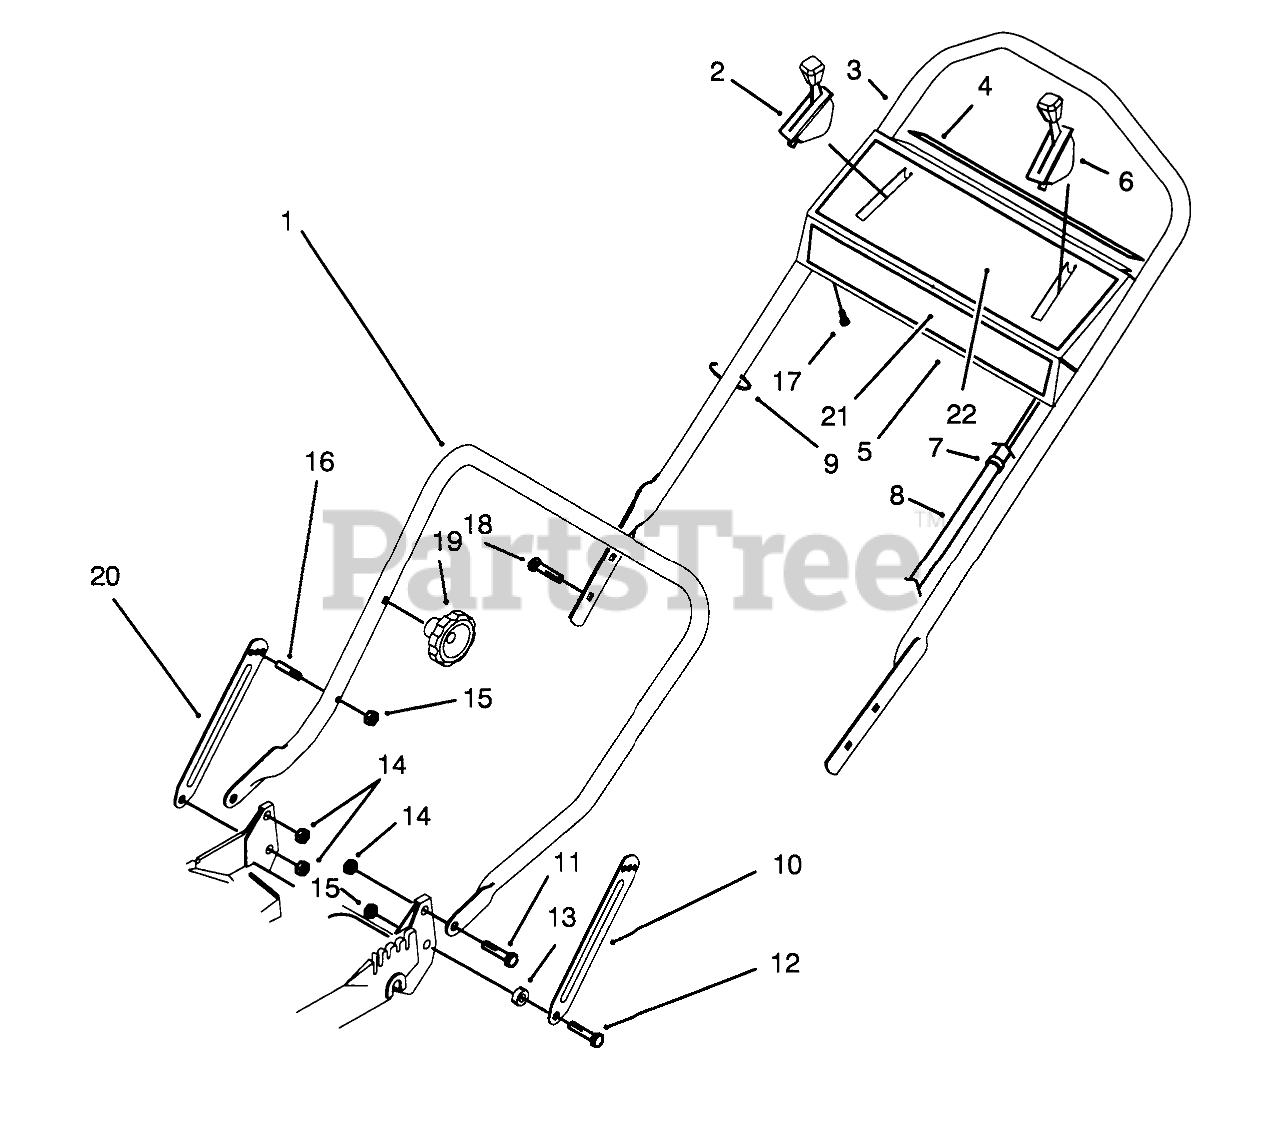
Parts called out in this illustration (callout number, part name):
1	LOWER HANDLE ASM
2	CONTROL-SPEED, GROUND
3	UPPER HANDLE, PVC DIP
4	DECAL-PANEL, REAR
5	Panel-Control(Incl. Ref. #4 & 22)
6	THROTTLE CONTROL
7	FITTING-RING
8	CONTROL CABLE COVER
9	TIE-CABLE
10	LH HANDLE LATCH
11	SCREW-SHOULDER
12	SCREW-SHOULDER
13	SPACER
14	NUT-LOCK, NI
15	NUT-LOCK, NI
16	HANDLE PIN
17	10-16X1/2 SHWH SCREW
18	5/16-18 X 2 HNDLE SCREW
20	RH HANDLE LATCH
21	DECAL - PANEL (TORO)
22	DECAL - INSTRUCTION
